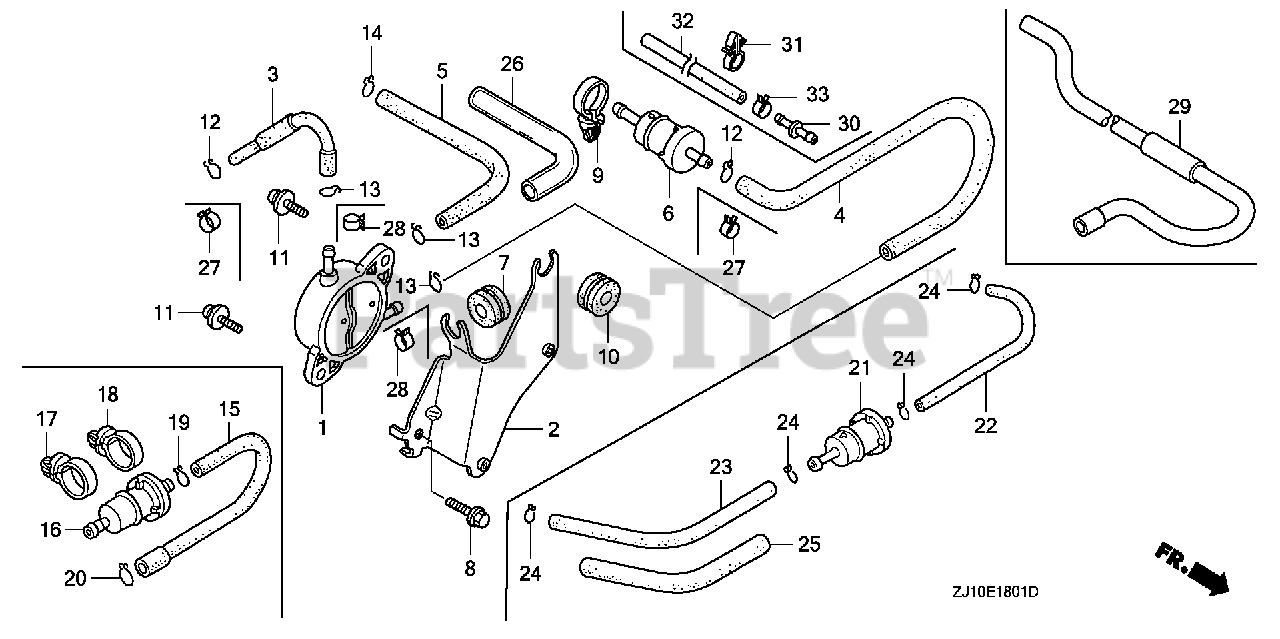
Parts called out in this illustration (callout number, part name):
1	PUMP ASSY., FUEL
2	STAY, FUEL PUMP
3	TUBE, FUEL (A)
4	TUBE B, FUEL
5	TUBE, DIAPHRAGM
6	FILTER, FUEL
7	GROMMET, RESERVE TANK
8	BOLT, FLANGE (6X14) (CT200)
9	CLIP, WIRE HARNESS
10	GROMMET, PUMP STAY
11	SCREW-WASHER (6X16)
12	CLIP, TUBE (B8)
13	CLIP, TUBE (B10)
14	CLIP, TUBE (B8)
14	CLIP, TUBE (C9)
